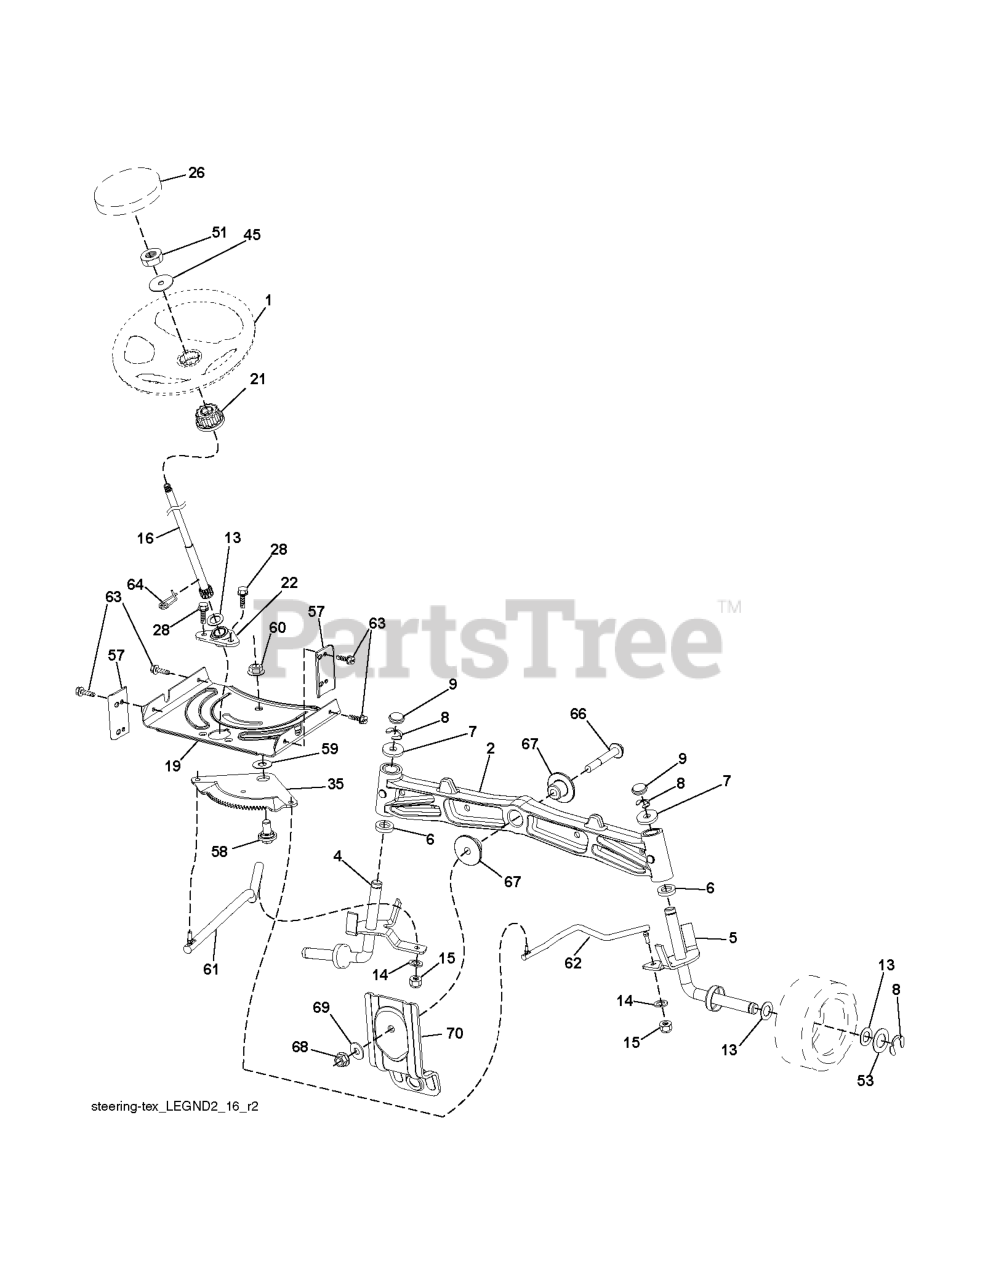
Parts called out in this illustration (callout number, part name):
1	RP WHEEL.STEER.HUSQ.PREM.OVMLD
2	AXLE.CAST.IRON
4	SPINDLE.WELDED.LH.15"TEX
5	SPINDLE.WELDED.RH.15"T
6	THRUST WASHER
9	CAP.SPINDLE.BLACK
14	WASHER, LOCK 3/8
15	NUT CROWNLOCK 3/8-24
16	SHAFT.STEER.STEALTH.DD
19	PLATE.STEER.DDL.NLT/NG
21	ADAPTER, WHEEL STNG..
22	BUSHING.ASM.STEERING.A
26	RP INSERT.CAP.WHL.STRG.HUSQ.
28	SCREW, 3/8-16X3/4
35	GEAR.SECTOR.PLATE.DDL.
45	WASHER 9/16"ID, 2 3/8"OD
51	NUT.HEX.1/2-20
53	WASHER.HARDENED
57	BRACKET.UPSTOP.TEX
58	BOLT.SHOULDER.SECTOR.P
59	WASHER.THURST.SECTOR.S
60	NUT FLANGE LOCK 5/8-11
61	DRAGLINK.LH.BALLSTUD.D
62	DRAGLINK.RH.BALLSTUD.D
63	SCREW
64	RETAINER.CLIP.SPRING.S
66	BOLT HEX FGHD 7/16-14 X 3 SERR
67	BUSHING.PM.FRONT AXLE
68	NUT.LOCK.FLANGE.7/16
69	WASHER.1.5X.505X.118
70	BRKT.DECK.SUSPENSION.F
